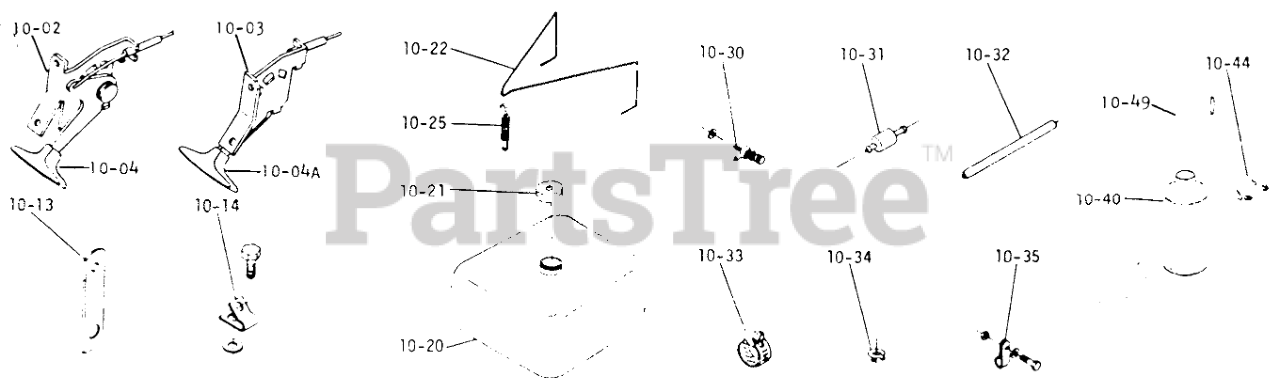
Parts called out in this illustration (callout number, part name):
10-02	Choke Control
10-03	THROTTLE CONTROL
10-04	KNOB-CHOKE
10-04A	KNOB-THROTTLE
10-13	Strap
10-14	THROTTLE CONTROL CLP
10-20	Tank-Fuel
10-21	Cap
10-22	HOLD DOWN WIRE
10-25	CLUTCH SPRING
10-30	S/A FUEL VALVE
10-31	Filter
10-32	Fuel Hose
10-33	CLAMP
10-34	Clamp
10-35	CLAMP-HOSE
10-40	MUFFLER
10-44	ASSY-MUFFLER CLAMP
10-49	MUFFLER INLET TUBE
